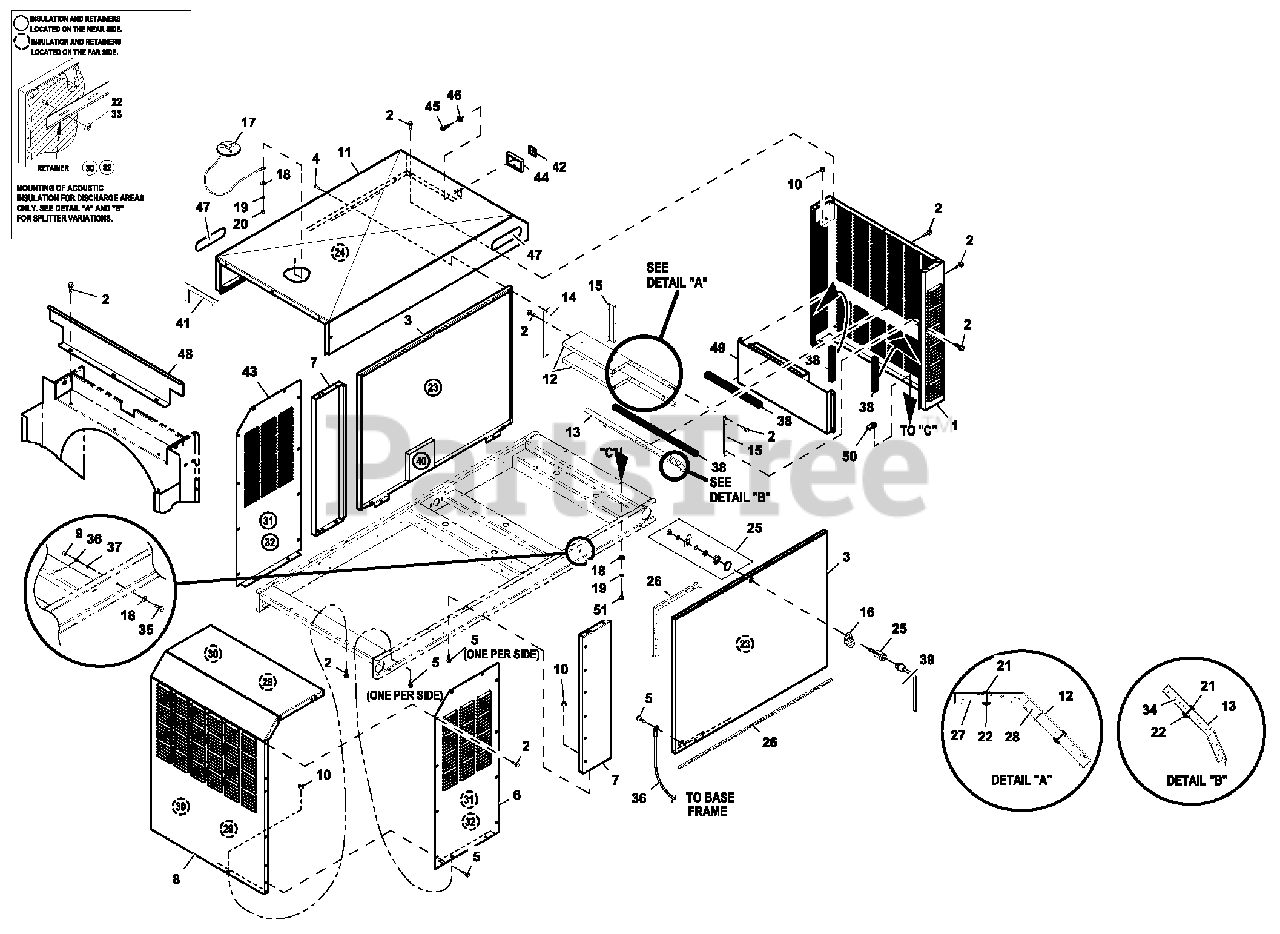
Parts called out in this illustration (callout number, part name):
1	REAR WRAP C2 CPL
2	SCREW THF M6-1 X 16 N WA Z/JS
3	D OOR C2
4	RIVET POP.1875 X .450 SS
5	SCREW TH-FRM M6 W/CAP SHKPRF W
6	D UCT DISCHARGE LH C2 AL
7	FRONT CORNERS C2
8	D UCT DISCHARGE MI D C2
9	NUT HEX M 6X1.0 G8 YELCHR
10	NUT HEX LOCK M6-1.0 SS NY INS
11	ROOF C2 CPL PVT LBL
12	SLITTER C4
13	SPLITTER LOWER C4
14	SPLITTER STRINGER C2
15	SUPPORT SPLITTER LHC2
16	PULL TAB D OOR LOCK SS
17	ASSEMBLY COVER ACCESS
18	WASHER FLAT 1/4-M6 ZINC
19	WASHER LOCK M6-1/4
20	NUT HEX 1/4-20 STEEL
21	INSULATION RETAINMENT HANGER
22	WASHER SELF LOCKING DOME #4-40
23	INSULATION D OOR C2
24	INSULATION ROOF TOP
25	VISE-ACTION LATCH SLOTTE D CIR
26	GASKET EXTRUDED TRIM (328" LG)
27	INSULATION SPLITTER
28	INSULATION SPLITTER
29	INSULATION D UCT
30	RETAINER INSULATION (820)
31	INSULATION D UCT SI D ES
32	RETAINER INSULATION (450)
33	WASHER SELF LOCKING DOME #8-32
34	INSULATION LOWER SPLITTER
35	SCREW HHC M6-1.0X20 G8.8
36	ASSY WIRE 14 AWG 34.8" GRN/YEL
37	WASHER SHAKEPROOF INT 1/4
38	TAPE FOAM 1X1 (150" LG)
39	KEY VISE-ACTION LATCH SLOT CIR
40	FOAM 300 X 300 THERMAL ACO (APPLIES TO 4.2L UNITS ONLY)
41	STRIP SEALANT 1/8X 1 (44.52+LG)
42	RF COVER PLATE-PLASTIC- D RK GRY (OPTIONAL)
43	D UCT DISCHARGE RH C2 AL
44	ASSY ENCLOSURE GEN SI D E RF
45	SCREW PPPH M3X12
46	WASHER FLAT M3
47	BA DGE, HONEYWELL
48	BAFFLE TOP EXHAUST C2 HW
49	D EFLECTOR INTAKE 2.4L G2 TURBO
50	NUT UM6-1.0 GEOMET
51	SCREW HHFC M6-1.0X 2 0 G8.8
